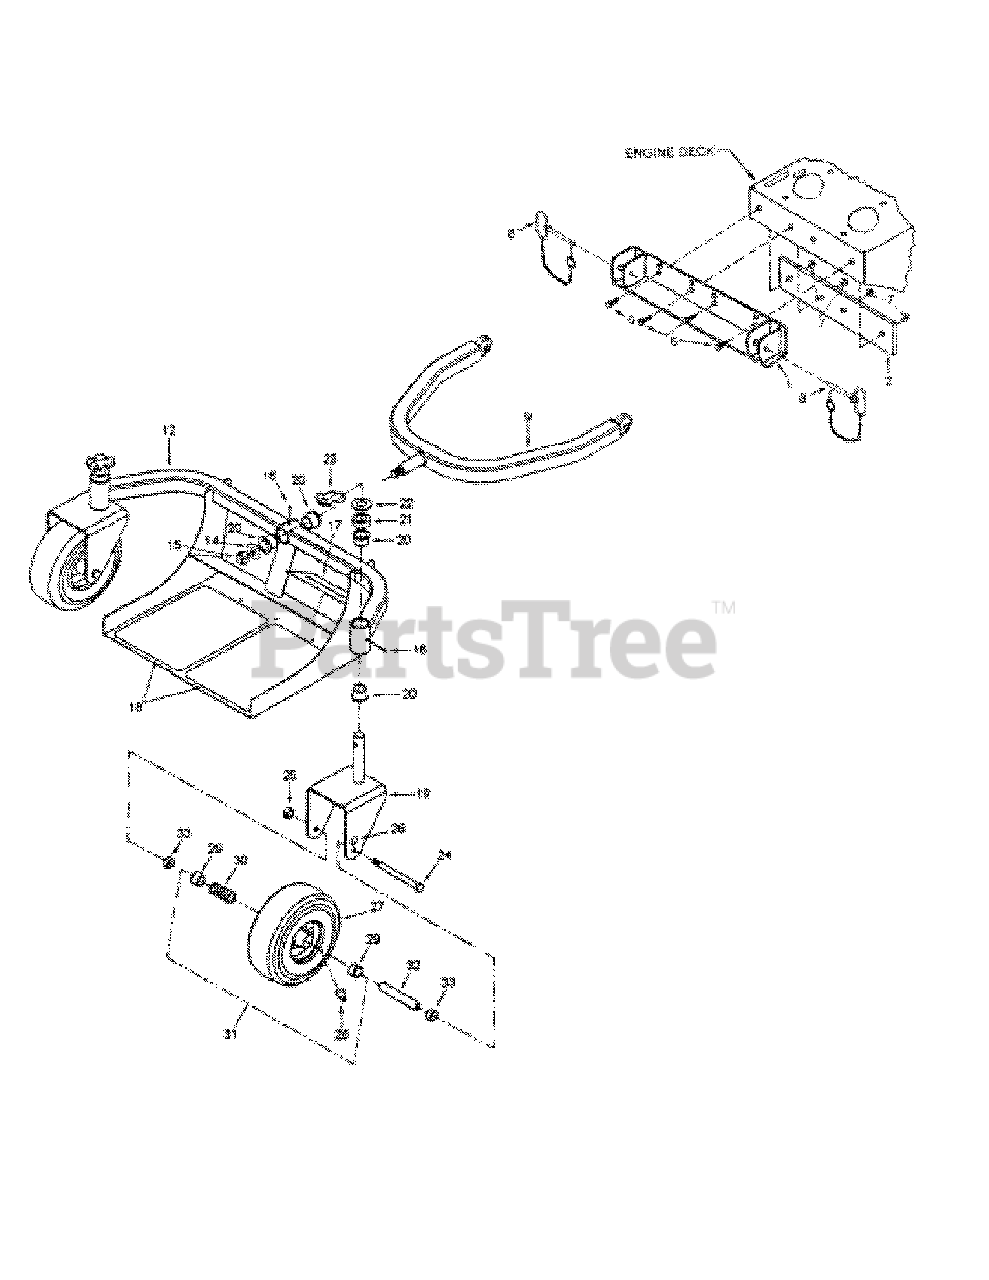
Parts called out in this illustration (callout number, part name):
1	Adapter Bar
2	Support Bar
6	Cap Screw, 3/8-16 x 1-1/4" Hex Hd.
7	Hex Nut, 3/8-16 Flanged Lock
8	Sulky Pin, 1/2"
9	Tubing, A-Frame
12	Footstand, Sulky
14	Flat Washer, .750 x 1.50 x .120 Thk.
15	Hex Nut, 3/4-16 Center Lock
16	Grease Fitting
17	Safety Decal
18	Foot Pad, Abrasive
19	Caster Fork
20	Flange Bearing, Bronze
21	Spacer, 1.013
22	Washer, Special
23	Pin, Klik
24	Cap Screw, 1/2-20 x 5.5 Hex Hd.
25	Hex Nut, 1/2-20 Center Lock
26	Decal, Inflation Info
27	Tire, 9.00 x 3.50 x 4 Smooth
28	Air Valve, Tubeless
29	Flange Bearing, Graf Oil
30	Roller Bearing
31	Wheel Assembly, Caster (1 each Ref. 27, 28 & 30 and 2 each Ref. 29)
32	Spacer, Wheel
33	Spacer, .812 ID x .268 LG
